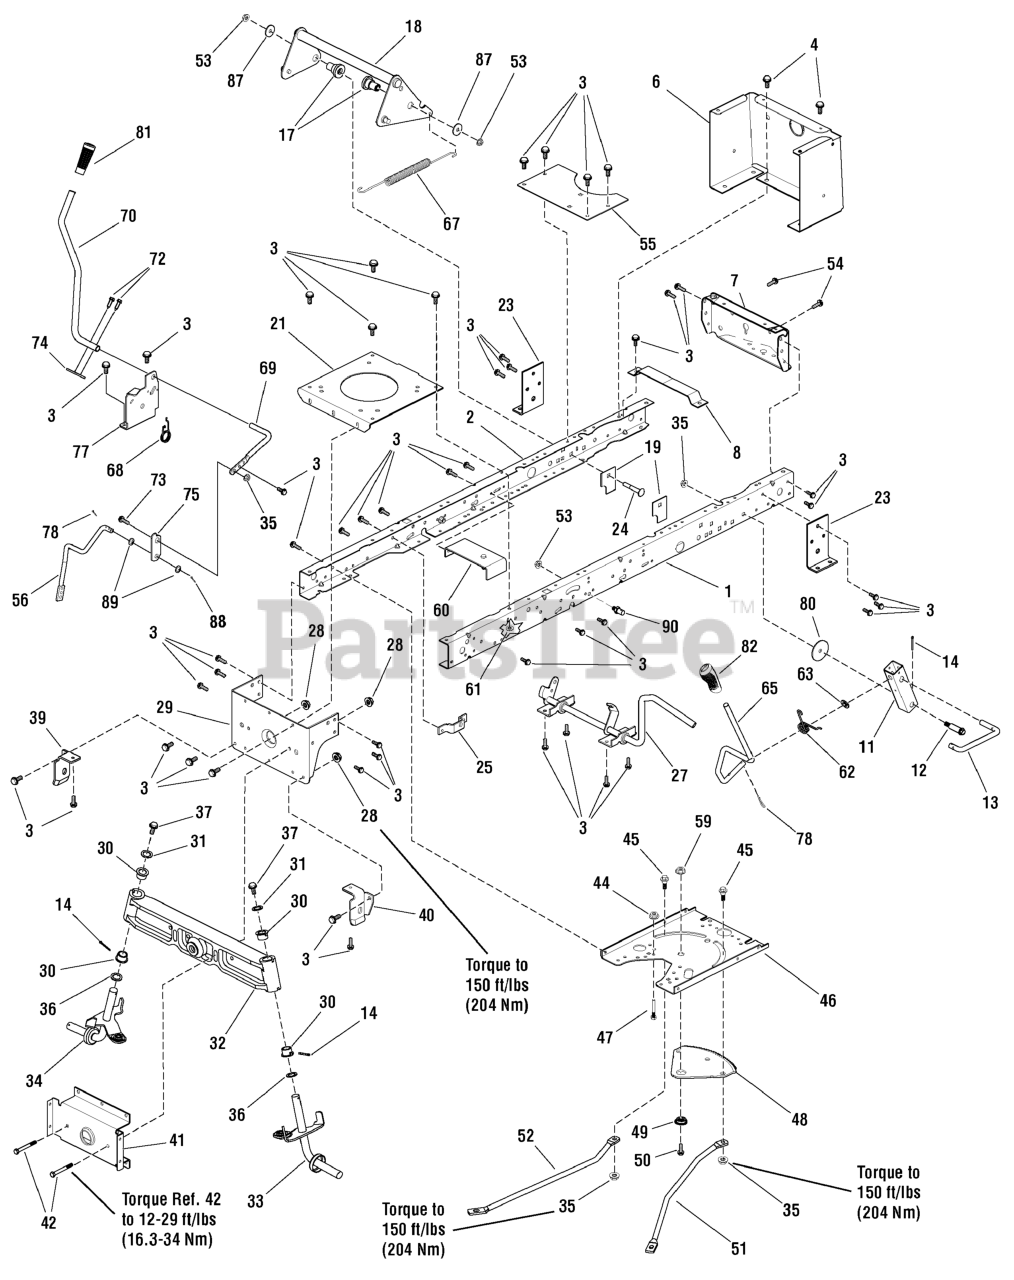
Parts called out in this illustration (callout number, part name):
1	FRAME, Left
2	FRAME, Right
3	CAPSCREW, 5/16-18 x 3/4
4	SCREW, Self Tap, SEMS, #10-24 x 1/2
6	PANEL, Rear
7	PLATE, Hitch
8	BRACKET, Battery Support
11	BRACKET, Pivot
12	BOLT, Shoulder, 3/8-16 x 1/2
13	LINK, Lift Handle
14	COTTER PIN, 1/8 x 1-1/4
17	SPACER, Lifter
18	LIFTER ASSEMBLY
19	PLATE, Stiffening
21	PLATE, Engine
23	BRACKET, Transaxle
24	BOLT, Carriage, 3/8-16 x 2-1/2
25	BRACKET, Bellcrank
27	BRAKE PEDAL
28	NUT, Hex Flange, 5/16-24
29	BRACKET, Rear Hanger
30	BEARING, Spindle, LT
31	WASHER, Flat
33	SPINDLE, Left
34	SPINDLE, Right
35	NUT, Hex Flange, 3/8-16
36	WASHER, Flat, 3/8
37	BOLT, Hex, 3/8-16 x 1-1/2
39	HANGER, Deck, R.H.
40	HANGER, Deck, L.H.
41	AXLE, Hanger
42	BOLT, Hex Head, 5/16-24 x 2-3/4
44	NUT, Hex Flange, 5/16-18
45	BOLT, Shoulder, 3/8-16 x 1
46	PLATE, Steering Mount
47	SCREW, Guide
48	GEAR, Sector
49	BEARING, Sector Gear
50	CAPSCREW, Hex Head, 5/16-18 x 1
51	DRAG LINK, Left
52	DRAG LINK, Right
53	NUT, Hex Flange, 3/8-16
54	SCREW, 3/8-16 x 3/4
55	PLATE, Idler Pulley
56	CRANK, PTO
59	NUT, Flange, 5/16-18
60	IDLER BRACKET ASSEMBLY, Secondary
61	NUT, Hex Flange, 5/16-18
62	SPRING, Torsion
63	WASHER, Flat, 1
65	HANDLE, Lift
67	SPRING, Extension
68	SPRING, Torsion, PTO
69	LEVER, PTO
70	HANDLE, PTO
72	SCREW, Thread Forming, 1/4-20 x 1
73	BOLT, Shoulder, 3/8-16 x 1/2
74	PADDLE, Switch, Yellow
75	LINK, PTO, Yellow
77	BRACKET, PTO
78	HAIRPIN
80	WASHER, Plain, 2-1/4
81	GRIP, PTO
82	GRIP, 1/2" Shaft, Tapered
87	WASHER, Flat, 3/4
88	COTTERPIN, 3/4
89	WASHER, Flat 3/4
90	PIN, Threaded Shoulder, 3/8-16 x 1-1/2
